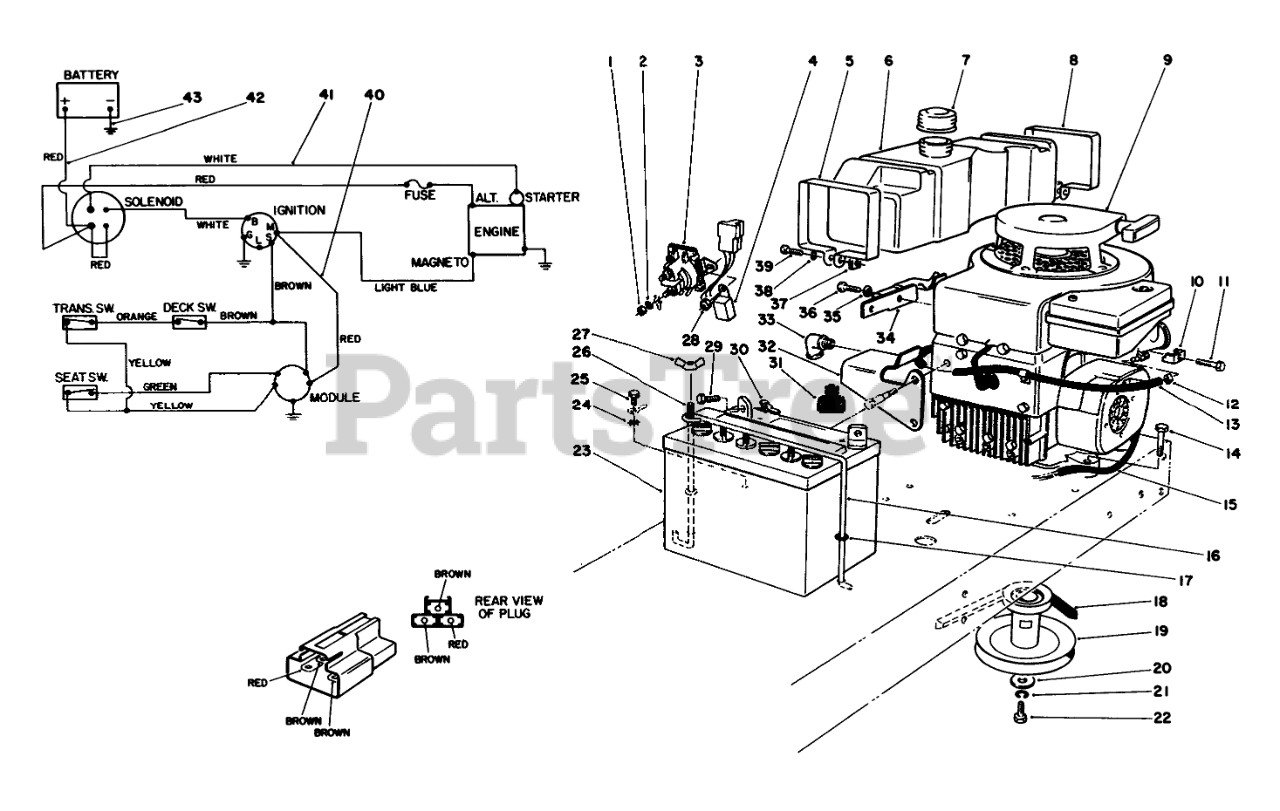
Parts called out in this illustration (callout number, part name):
1	NUT-JAM
2	WASHER-LOCK
3	SOLENOID
4	INTERLOCK MODULE
5	Retainer-Tank Front
6	TANK-5 QT GAS
7	GAS CAP ASM
8	Retainer-Tank Rear
9	Engine-8 H.P. (Model 56150)
10	CLAMP-CASING
11	SCREW W ENGINE
12	FUEL HOSE CLAMP
13	HOSE-FUEL
14	SCREW-HH
15	Cover-Protective
16	HOLDDOWN-BATTERY
17	O-RING
18	V-BELT, TRACTION
19	PULLEY
20	WASHER-FLAT
21	WASHER-LOCK
22	SCREW-HH
23	Battery
24	WASHER-LOCK, INTERNAL
25	SCREW-HHF
26	POST-BATTERY
27	NUT-WING
28	NUT-LOCK, CONE
29	SCREW-HH
30	NUT-WING
31	BOOT-TERMINAL
32	FRT TANK MTG BRKT B
33	ELBOW-STREET, 90 DEG
34	REAR TANK MTG BRKT B
35	WASHER-PLAIN
36	SCREW-HH
37	NUT-SQUARE
38	WASHER-LOCK
39	SCREW-HSH
40	WIRE HARNESS
41	STARTER WIRE HARNESS
42	WIRE ASM
43	WIRE ASM(BATT/GRD.
